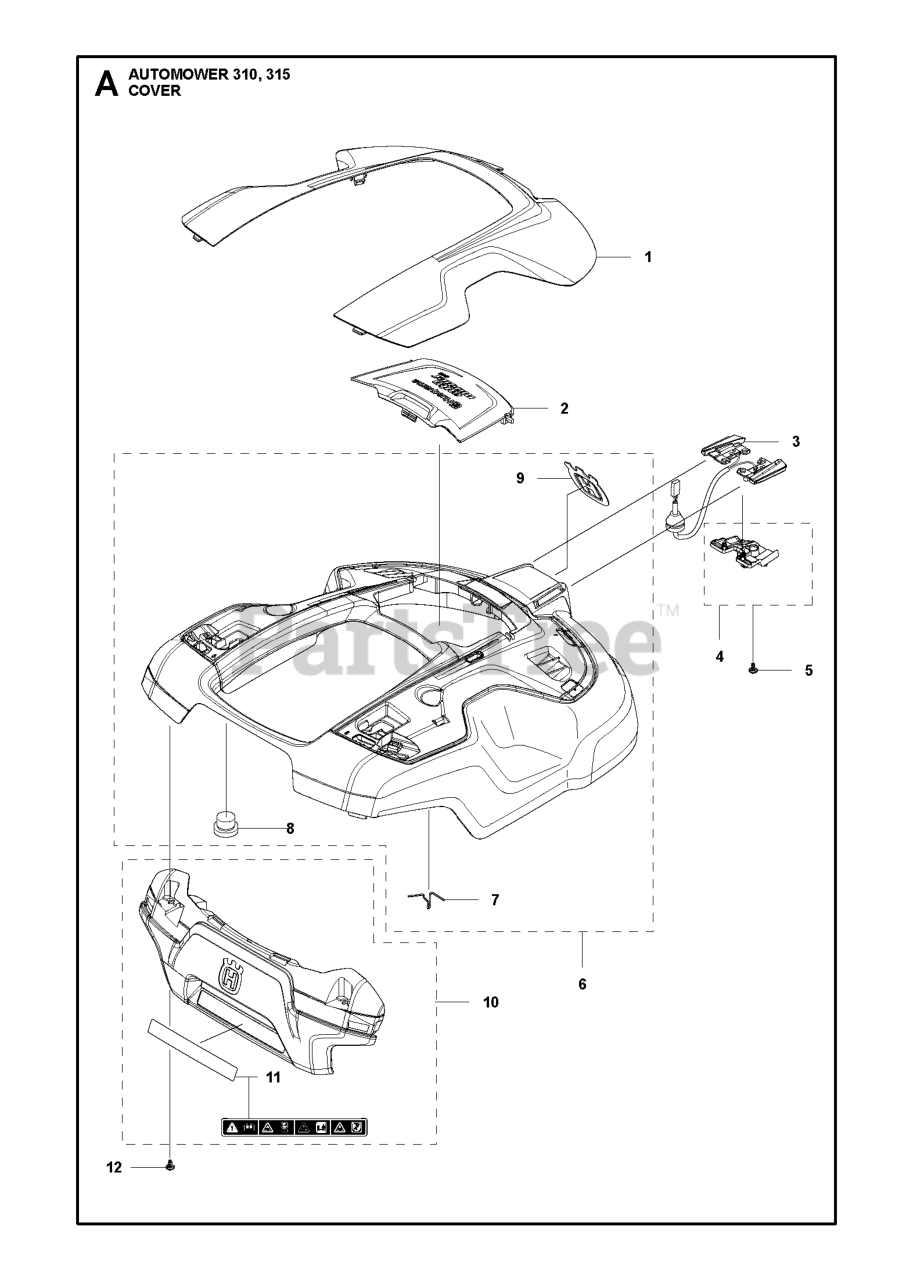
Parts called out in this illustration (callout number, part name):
1	GREY COVER
1	WHITE COVER
1	ORANGE COVER
2	HOOD 315
3	CABLE ASSY CHARGING PLATE
4	HOLDER KIT MAGNET
5	SCREW ITXPANT
6	BODY KIT
7	SPRING HOOD
8	CAP SNAPLOC
9	DECAL HUSQVARNA CROWN HEIGHT 5
10	BUMPER KIT
11	LABEL WARNING P15
12	SCREW ITXPANT
13	MAGNET NEODYMIUM D5X8
14	MAGNET NEODYMIUM D5X8
